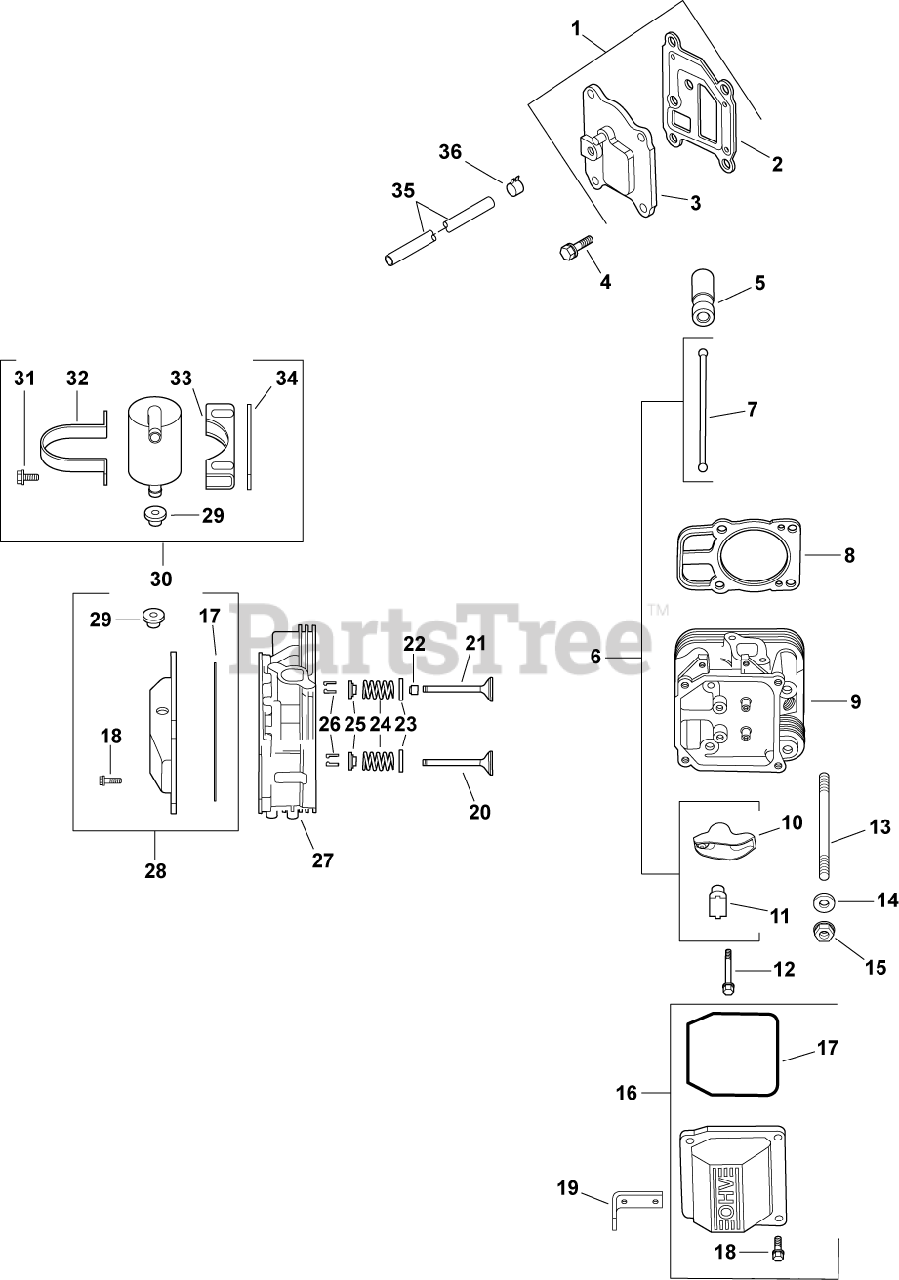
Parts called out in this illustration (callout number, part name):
1	KIT, BREATHER COVER W/GASKET
2	GASKET, BREATHER-USE 24 041 67-S
3	COVER, BREATHER -USE 24 096 125-S
4	SCREW,FLG THD FRM M6X1.0X20-(#25086396S)
5	LIFTER, HYDRAULIC VALVE-USE 25 351 10-S
6	KIT, VALVE TRAIN
7	ROD, PUSH
8	CYL HEAD GASKET KIT-USE 24 841 04-S
9	HEAD, ASSEM CYLINDER #2 -USE 24 318 119-
10	ARM, ROCKER
11	PIVOT, ROCKER ARM
12	SCREW, FLG M6X1.0X34
13	STUD, M8X1.25
14	WASHER, FLAT 8.6 MM
15	NUT, FLG M8X1.25
16	KIT, VALVE COVER-PLAIN
17	O-RING (YELLOW) -USE 24 153 30-S
18	SCREW, FLG M6X1.0X30
19	STRAP, LIFTING-USE 25 445 03-S
20	VALVE, EXHAUST (STD) - USE 32 016 01-S
21	VALVE, INTAKE (STD)
22	SEAL, VALVE STEM - (#2503214S)
23	RETAINER, SPRING
24	SPRING, VALVE
25	RETAINER, VALVE SPRING - USE 25 173 28-S
26	KIT, RETAINER
27	HEAD, ASSEM CYLINDER #1 -USE 24 318 111-
28	KIT, VALVE COVER
29	GROMMET, RUBBER
30	KIT, BREATHR SEPARATR-(#24755241S)
31	SCREW,FLG THD FRM M5X0.8X16-(#25086398S)
32	STRAP, BREATHER - USE 24 755 241-S
33	BRACKET, BREATHER SEPARATOR
34	SPACER
35	HOSE, BREATHER -USE 24 326 63-S
36	CLAMP, HOSE-USE 25 237 32-S
2401602-S	VALVE, EXHAUST (.25)
2401702-S	VALVE, INTAKE (.25)
